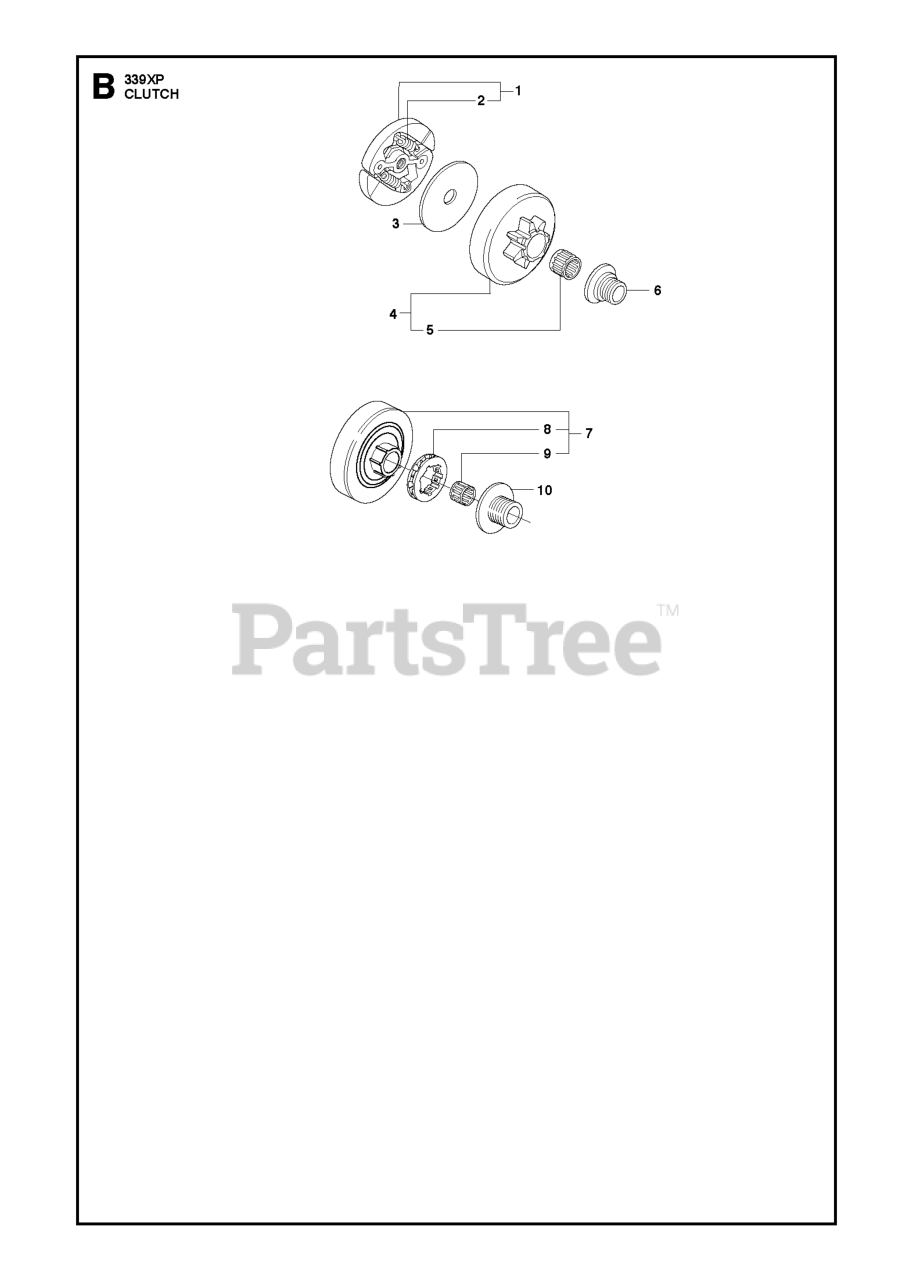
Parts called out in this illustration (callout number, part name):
4	CLUTCH DRUM
4	CLUTCH DRUM .325
4	CLUTCH DRUM 3/8
5	NEEDLE BEARING
6	PINION
6	OIL PUMP PINION
7	CLUTCH DRUM CPL
8	RIM SPROCKET 7T .325
9	NEEDLE BEARING
10	WORM GEAR
